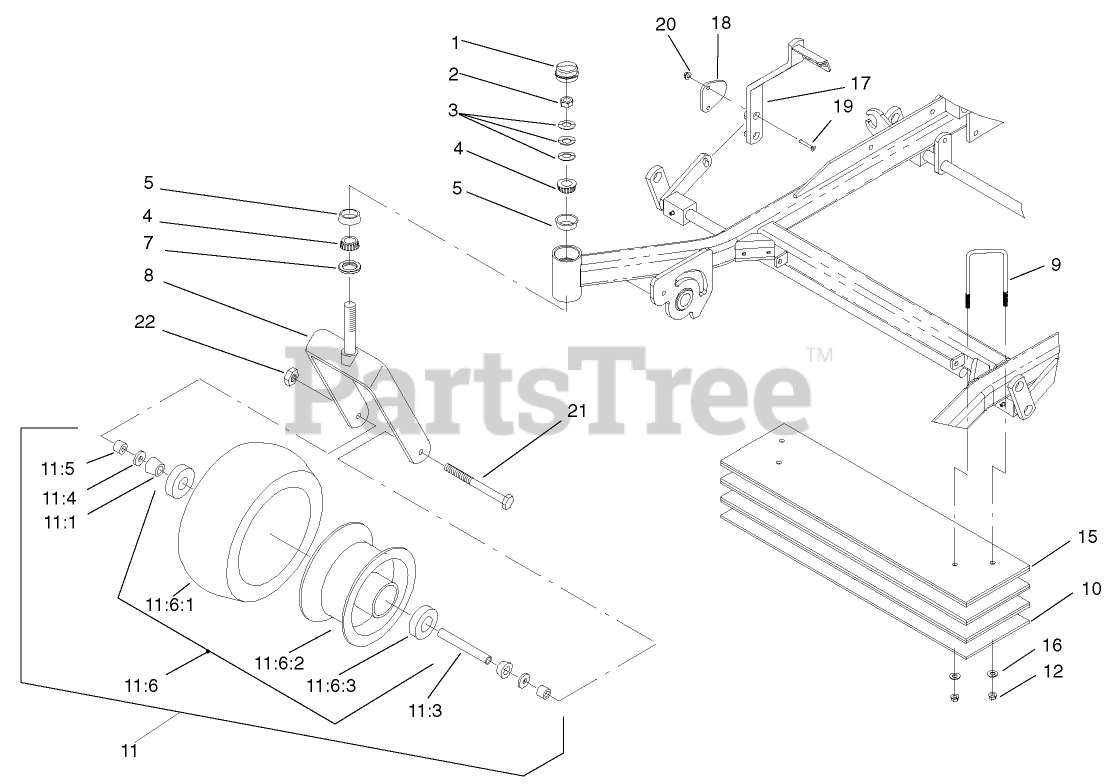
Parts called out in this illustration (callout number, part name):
1	CAP-GREASE
2	NUT-LOCK, NI
3	WASHER-BELLVILLE
4	BEARING-CONE, TAPERED
5	BEARING-CUP, TAPERED
7	SEAL-GREASE
8	CASTER
9	U-BOLT
10	BAR-WEIGHT
11	CASTER WHEEL ASM
11:1	BEARING-CONE, TAPER
11:3	SPACER-CASTER, FRONT
11:4	SEAL-BEARING
11:5	SPACER-BEARING
11:6	Wheel AND Tire ASM
11:6:3	BEARING-CUP
12	NUT-LOCK, NI
15	WEIGHT BAR ASM
16	WASHER-FLAT
17	LEVER-LIFT, DECK
19	SCREW
20	NUT-HF
21	SCREW-HH
22	NUT-LOCK, NI
